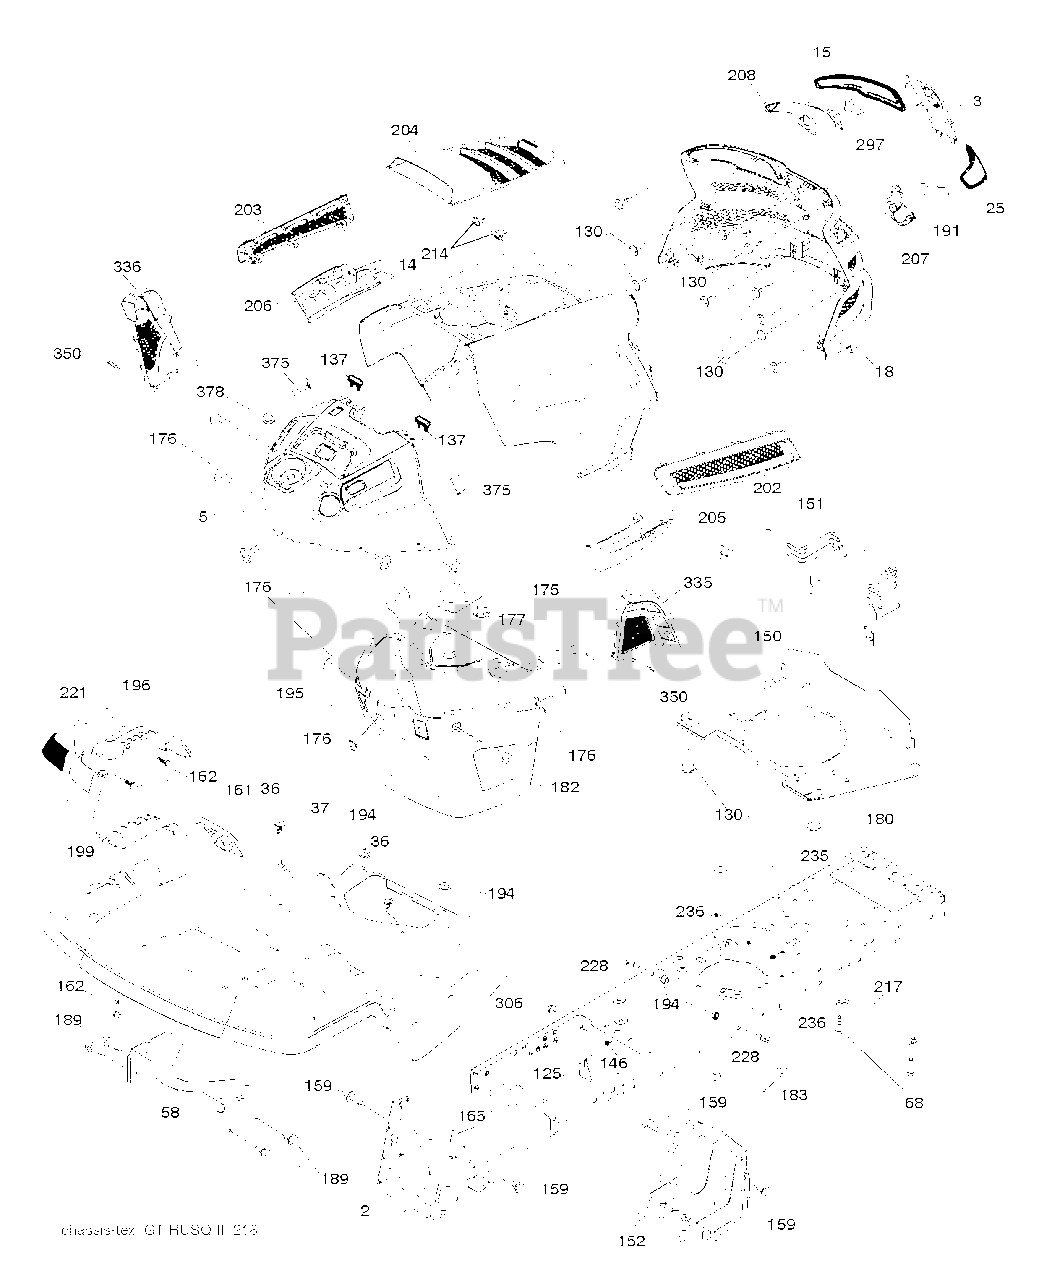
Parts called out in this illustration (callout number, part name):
2	DRAWBAR.STGT
3	APPLIQUE.SUBASM.GT.HUSQ.II
5	DASHBOARD.TEX.GT2.UPPER.S.PTO
14	HOOD.ASM.HUSQVARNA.GT.TEX.422
15	LENS.HEADLIGHT.LH.GTII.2011
18	GRILLE.SUBSTRATE.2011.
25	LENS.HEADLIGHT.RH.GTII.2011
36	SCREW 5/16"
37	FENDER.PNT.TX.GT.CH/FW/DL.HUSQ
58	BRKT.SUPPORT.FNDR/TANK
68	SCR 5/16-18 X 1/2 SELFTAP ZN
125	CLIP.FUEL.LINE
130	SCREW.#10 X 0.750.BOS
137	BUMPER DASH
146	BOLT.RDHD.SHT.SQNK.3/8-16X5/8
150	AIR.DUCT.GTV.BLACK
151	BRACKET.PIVOT.HOOD.GT.HUSQ.II
152	SHIELD.BROWNING.PNT.GT.V2
159	SCREW, 3/8-16X3/4
161	CONSOLE.WINDOW.FUEL.HUSQ.GT
162	SCREW.HI-LO.CONSOLE
165	SUPPORT.TANK.REAR.B/TE
175	Crossmember Plate
176	SCREW.#10-24X5/8.RN.QU
177	BUSHING STEERING
180	CHASSIS.LT/GT.BOLTED
182	DASH.LOWER.COMMON.12V.ADAPTOR
183	BOLT.5/16-18X1-1/4 FULL THD
189	SCREW
191	INSERT.REFLECTIVE.RH.HUSQ.GTII
194	NUT LOCK HEX FLANGE 5/16-18
195	PLUG.HOLE.DASH.LOWER.12V.BLK
196	CONSOLE.ASM.DECKLIFT.HUSQGT.DL
199	PLATE.DECK.LIFT.HUSQVARNA.GT
202	VENT.SIDE.RH.GT.HUSQ.II.
203	VENT.SIDE.LH.GT.HUSQ.II.498
204	VENT.TOP.HUSQ.GT2
205	SIDE.TRIM.RH.GT.HUSQ.II
206	SIDE.TRIM.LH.GT.HUSQ.II.GRAY
207	BEZEL LIGHT.RH.GT.II.MYLAR
208	BEZEL LIGHT.LH.GT.II.MYLAR
214	CLIP.RETAINER.TINNER.
217	ROD.PIVOT.HOOD
221	REFLECTOR.LH.TEX GT HU
228	STUD.FASTNER.W/ANTI-ROTATE
235	SPACER FENDER
236	NUT.CENTERLOCK.5/16-
297	INSERT.REFLECTIVE.LH.HUSQ.GTII
306	NUT LOCK FLG 3/8-16 UNC
335	COVER.LOWER.DASH.RH.BLACK
336	COVER-LH.LOWER.DASH.GT2.BLACK
350	KIT GUARD BRUSH
375	BUMPER CLIP-ON. DASH 1"
378	BUSHING FLANGE; PLASTIC
